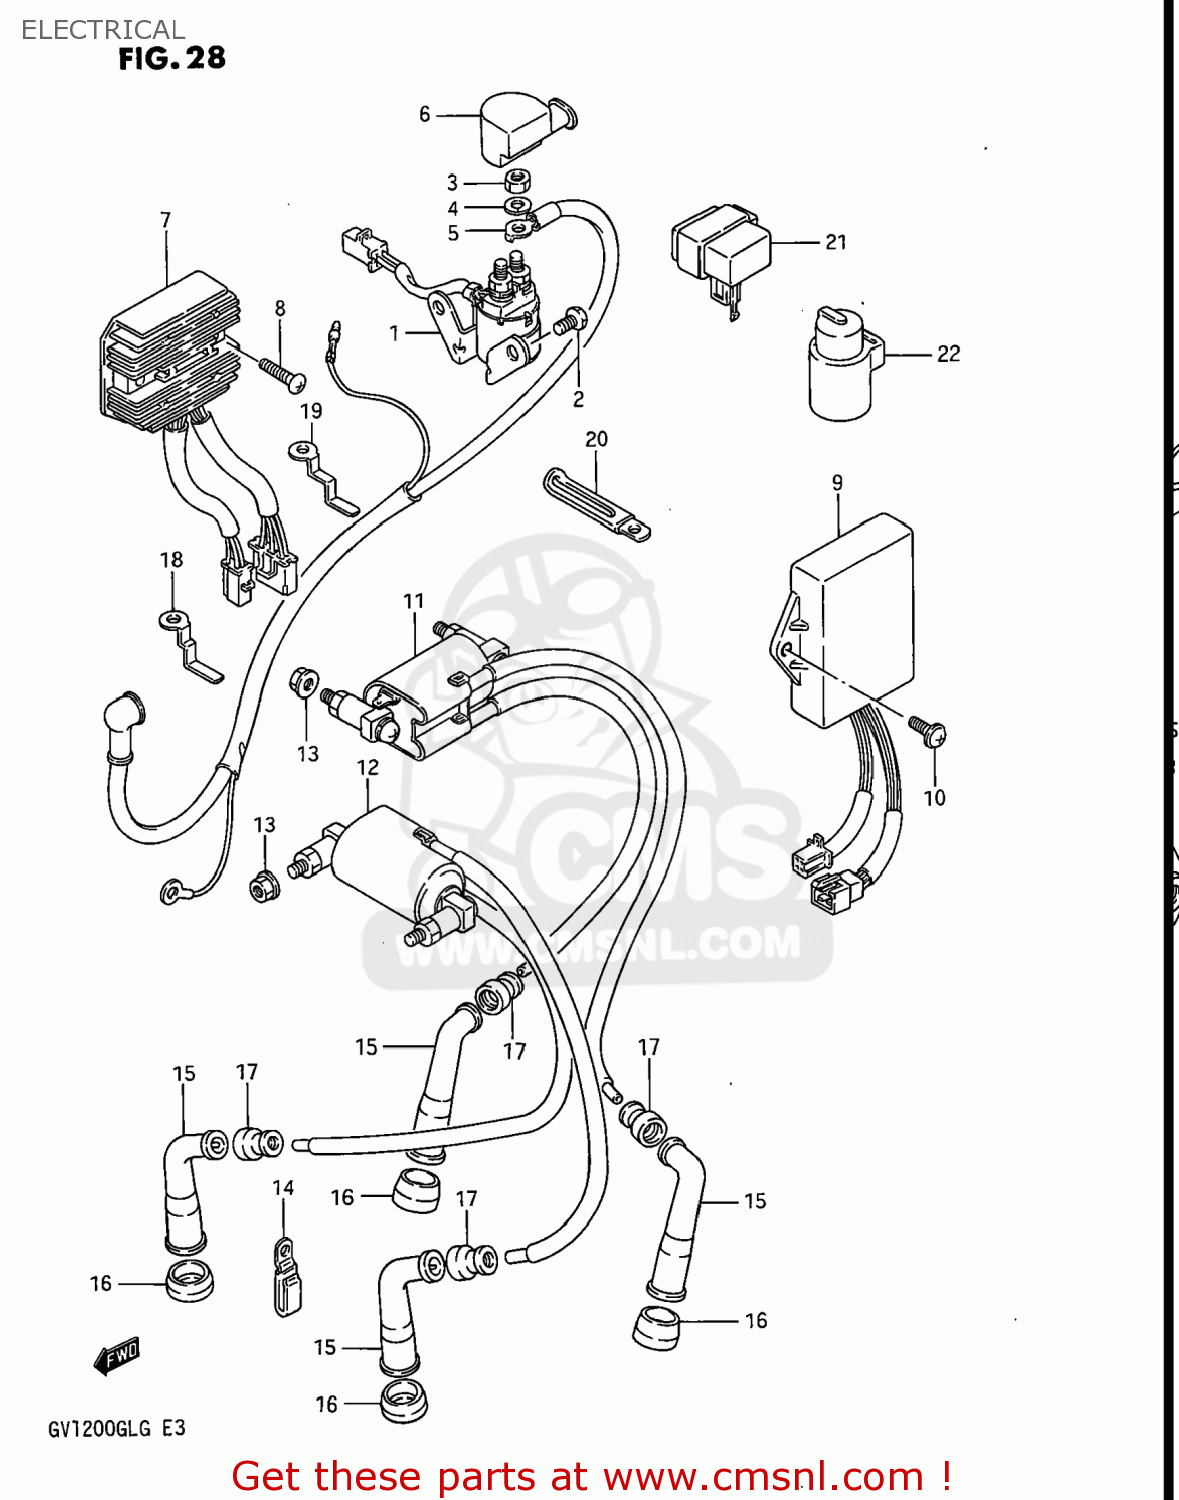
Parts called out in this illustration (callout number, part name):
1	RELAY ASSEMBLY,STARTING MOTOR
2	BOLT
3	NUT
4	WASHER,LOCK
5	WIRE,STARTER MOTOR
6	CAP,STARTER RELAY TERMINAL
7	RECTIFIER ASSY
8	SCREW
9	IGNITER UNIT
10	SCREW 6X12
11	COIL ASSEMBLY,IGNITION
12	COIL ASSEMBLY,IGNITION
13	NUT
14	CLAMP
15	CAP ASSY,SPARK PLUG
16	SEAL,SPARK PLUG
17	SEAL,SPARK PLU
18	CLAMP,WIRING HARNESS
19	CLAMP,WIRING HARNESS
20	CLAMP
21	CIRCUIT,OPENING RELAY
22	RELAY ASSEMBLY,THERMOMETER
